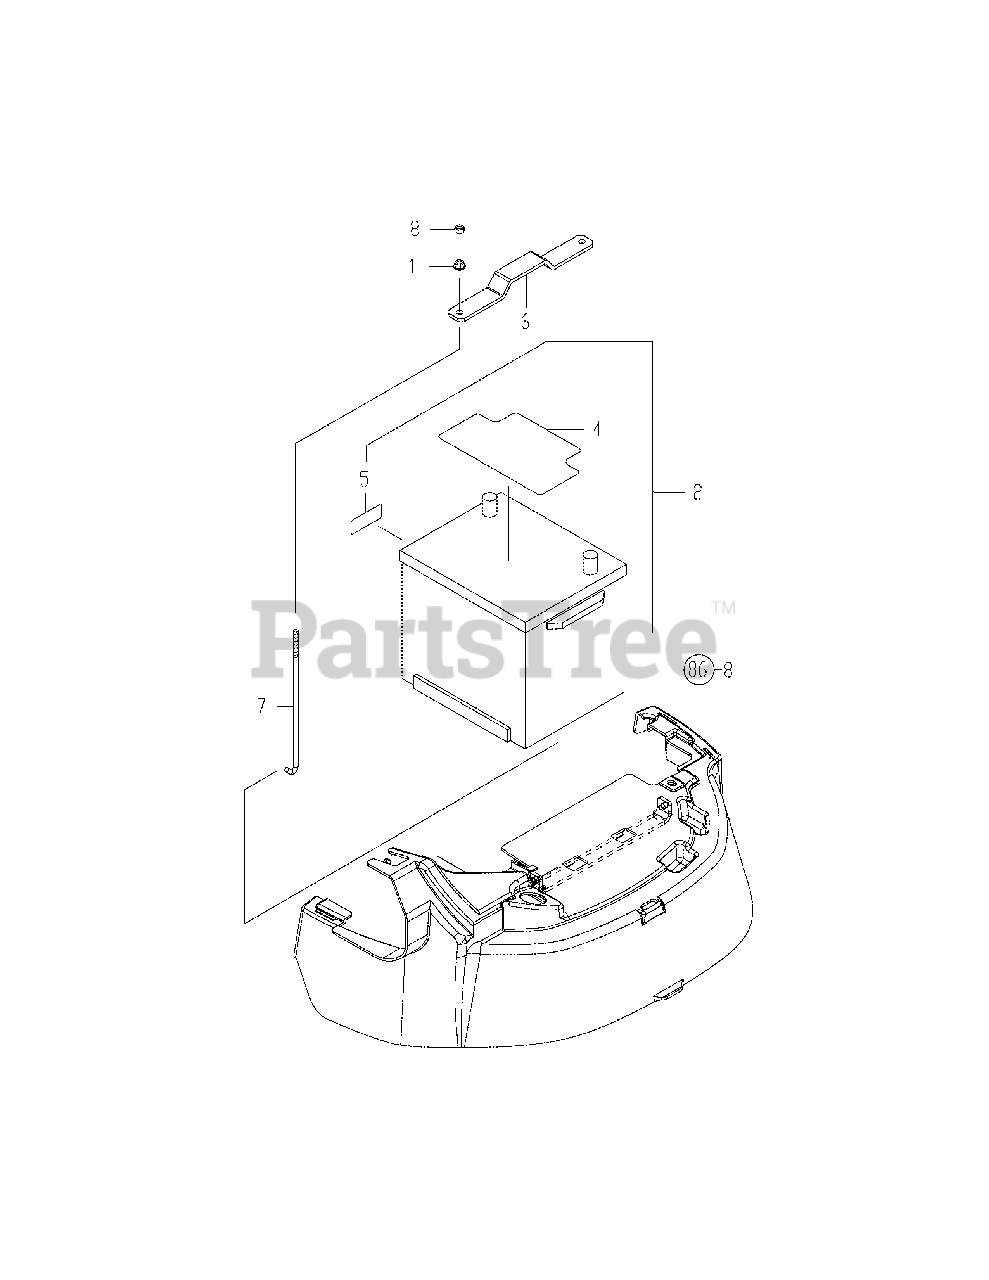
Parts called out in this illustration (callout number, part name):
2	Battery, 26R, Assy
4	Label, Battery
5	Label,Ca,65, Warn
6	Clamp, Battery
7	Rod, Battery Clamp
